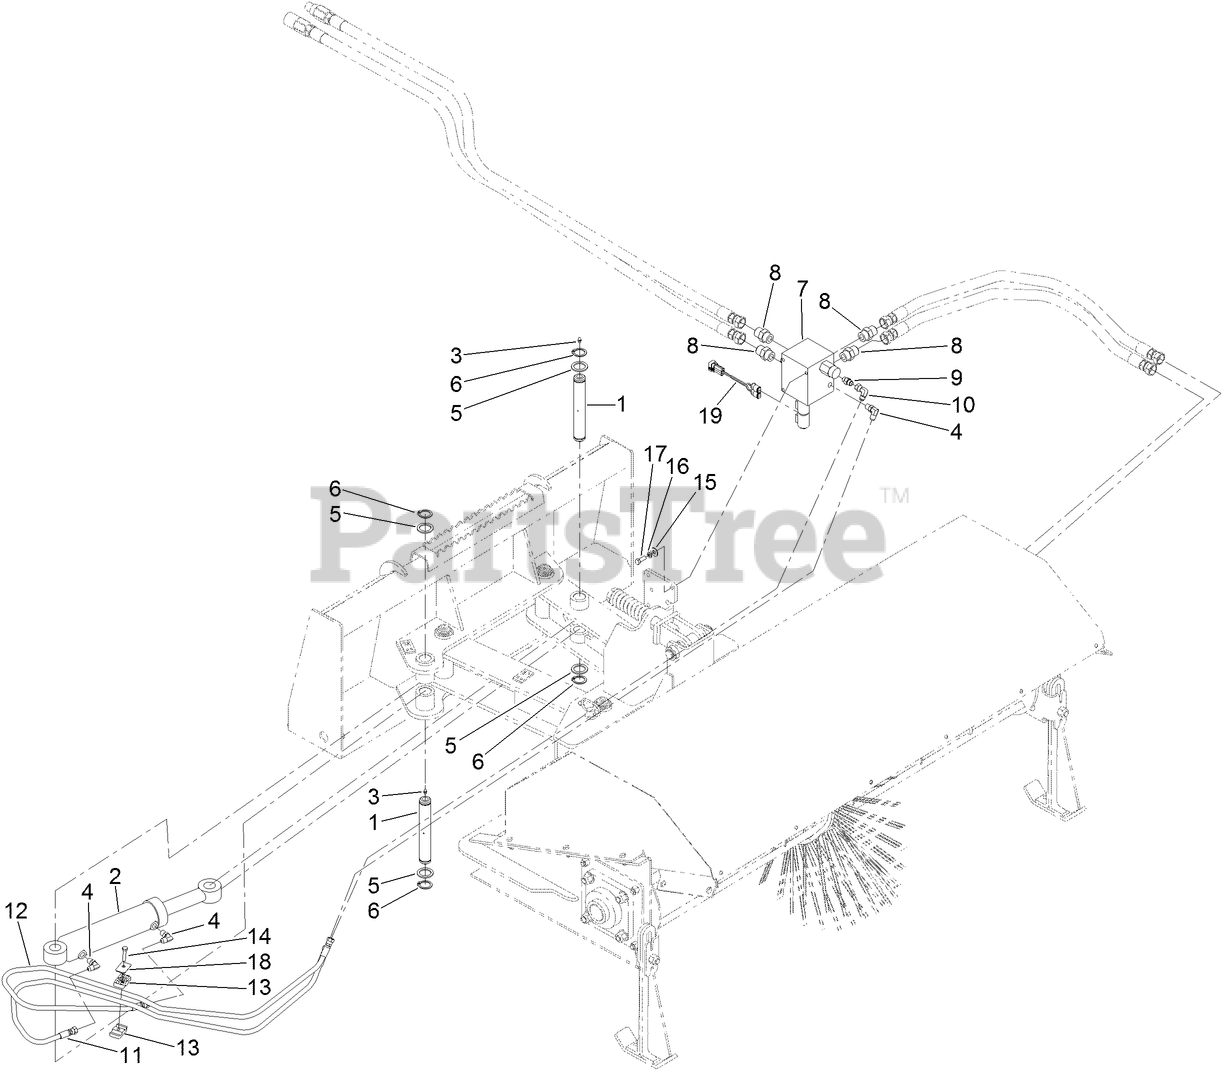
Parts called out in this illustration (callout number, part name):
1	PIN-PIVOT
2	HYDRAULIC CYLINDER ASM
3	FITTING-ZERK
4	FITTING-ELBOW
5	WASHER-STEERING
6	RING-RETAINING, EXTERNAL
7	HYDRAULIC MANIFOLD ASM
8	FITTING-STRAIGHT
9	FITTING,STRAIGHT,6-MORB X 6-M37JIC
10	ELBOW-SWIVEL, 90 DEG
11	HYD HOSE ASM
12	HYD HOSE ASM
13	CLAMP-TUBE
14	SCREW-HH
15	WASHER-FLAT
16	WASHER-LOCK
17	SCREW-HH
18	COVERPLATE
